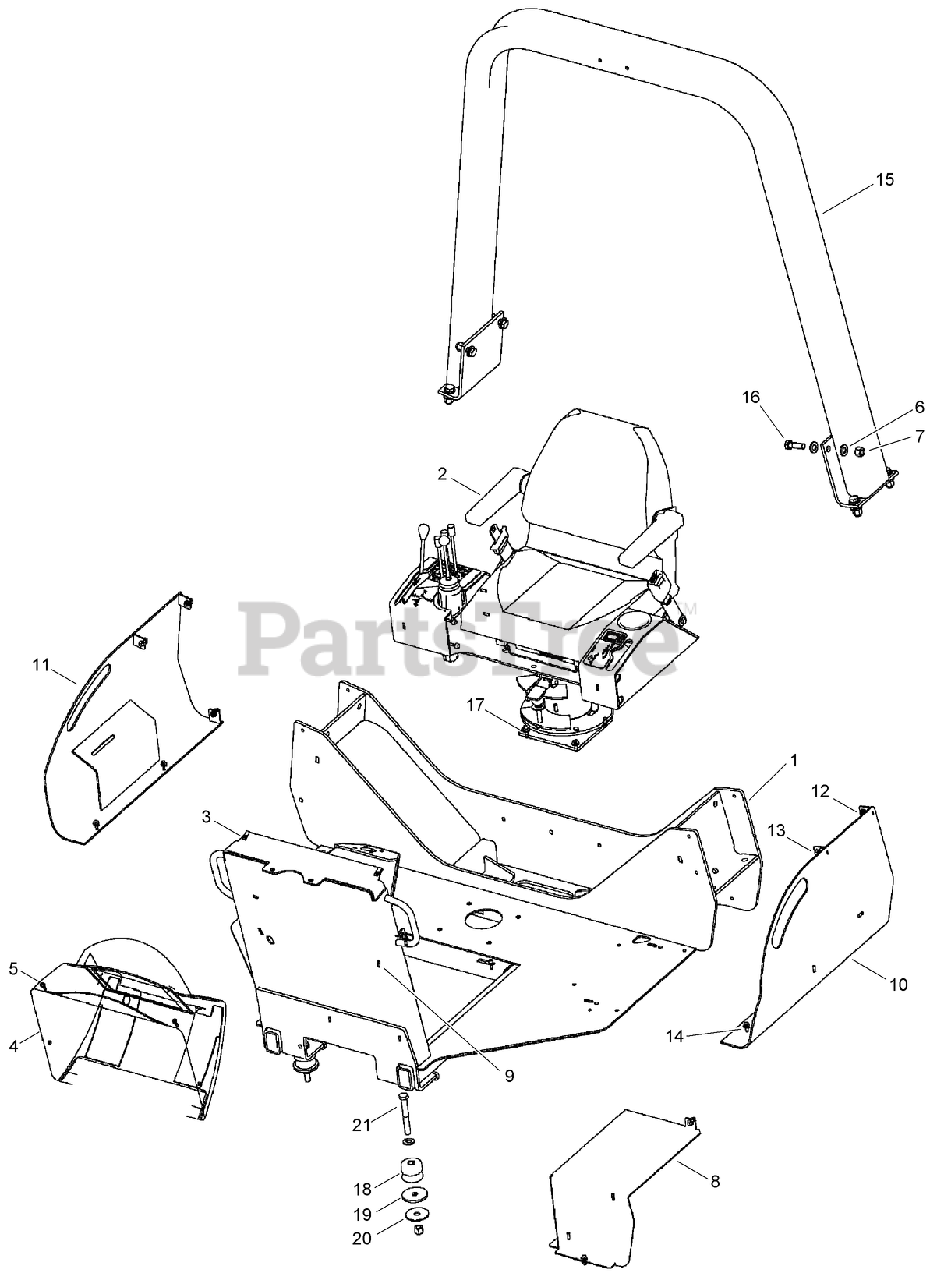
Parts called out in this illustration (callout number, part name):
1	WELDMENT-Operators Platform
2	ASM-Seat
4	PANEL-Dash
5	SCREW, METRIC FLANGE w/BODY-M6 x 25
6	WASHER-FLAT
7	NUT-LOCK, HEX
8	COVER-Battery
9	PLATE-Kick
10	WELDMENT-Fender, LH
11	WELDMENT-Fender, RH
12	SCREW-HH
13	NUT, METRIC HEX FLANGE - M8, Zinc
14	SCREW, METRIC FLANGE w/BODY - M8 x 20
16	BOLT-Hex Hd 0.625 x 2.00 GR8 ZND
17	SCREW-FLANGE
18	MOUNT-REAR
19	WASHER-SNUBBING
20	WASHER
21	SCREW-HH
